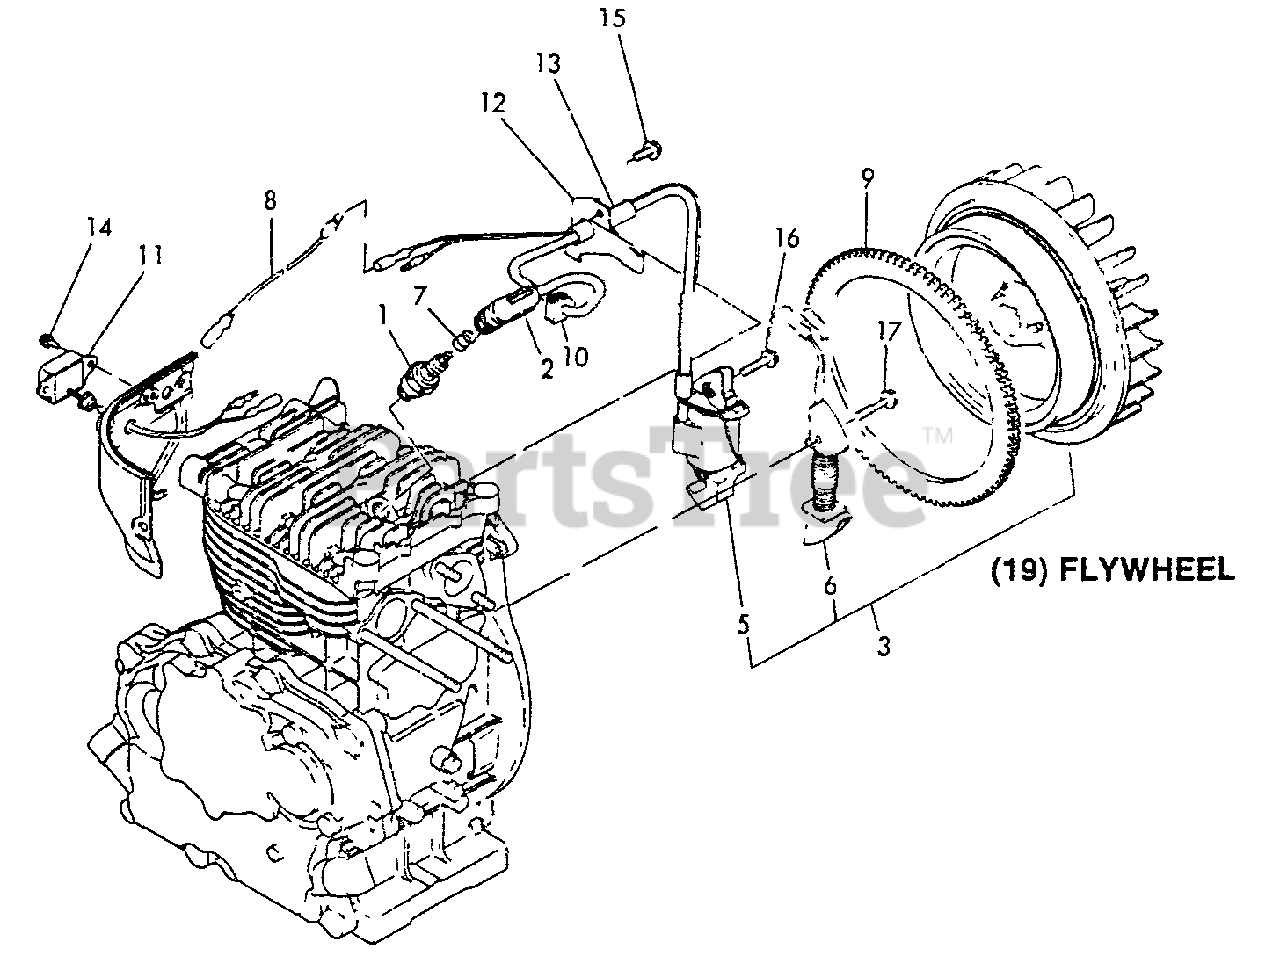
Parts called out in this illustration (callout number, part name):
1	SPARK PLUG
2	CAP, PLUG
3	FLYWHEEL W/MAGNET
5	COIL, IGNITION
6	COIL, CHARGE
7	TERMINAL, SPARK PLUG CAP
8	WIRE
9	GEAR, RING
10	GROMMET
11	IGNITER
12	CLAMP
13	TUBE, INSULATOR
14	SCREW - 5×10
15	BOLT - 6×8 -- PLATED
16	BOLT - 6×30
17	BOLT - 6×30
